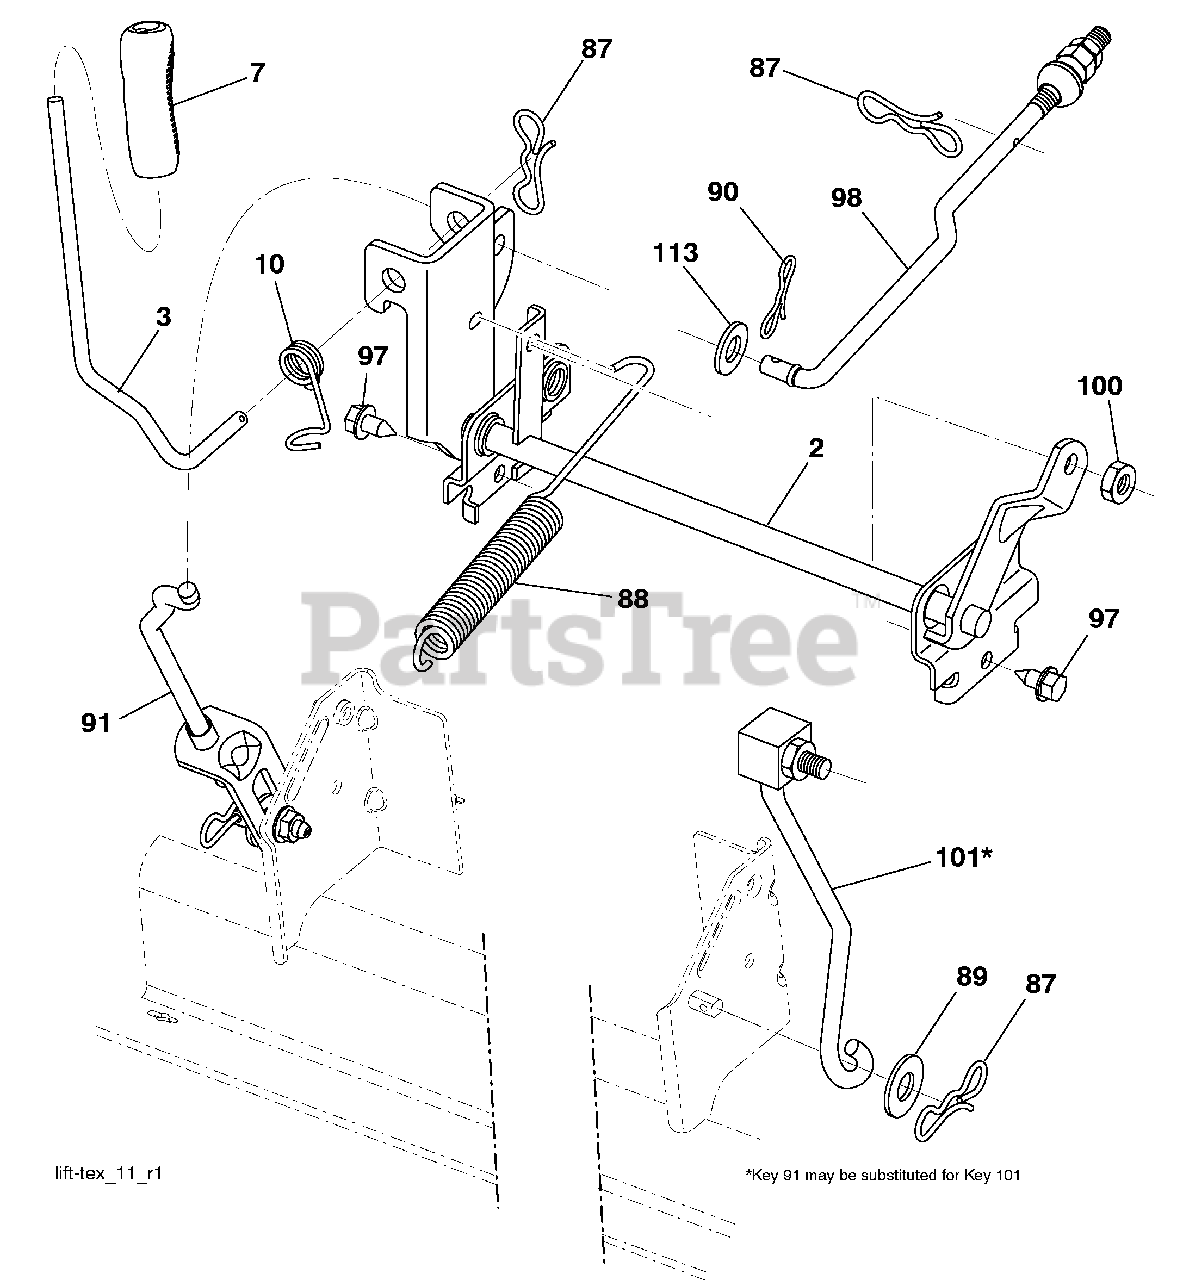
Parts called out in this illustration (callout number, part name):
2	Shaft Asm., Lift
3	Lever Asm., Lift RH
7	Grip, Lever
10	Spring Torsion
87	Pin Cotter 7/16 Bow Tie Lock
88	Spring Lift Assist
89	Washer Clear
90	Pin Cotter 5/16 Bow Tie Lock
91	Link Lift Susp Mower Rear
97	Screw 3/8-16 x 3/4
98	Link Lift Susp. Front Mower
100	Nut Centerlock 3/8-16
101	Link Asm. Lift FXD
113	Washer 17/32 x 1-3/16 x 12 Ga.
